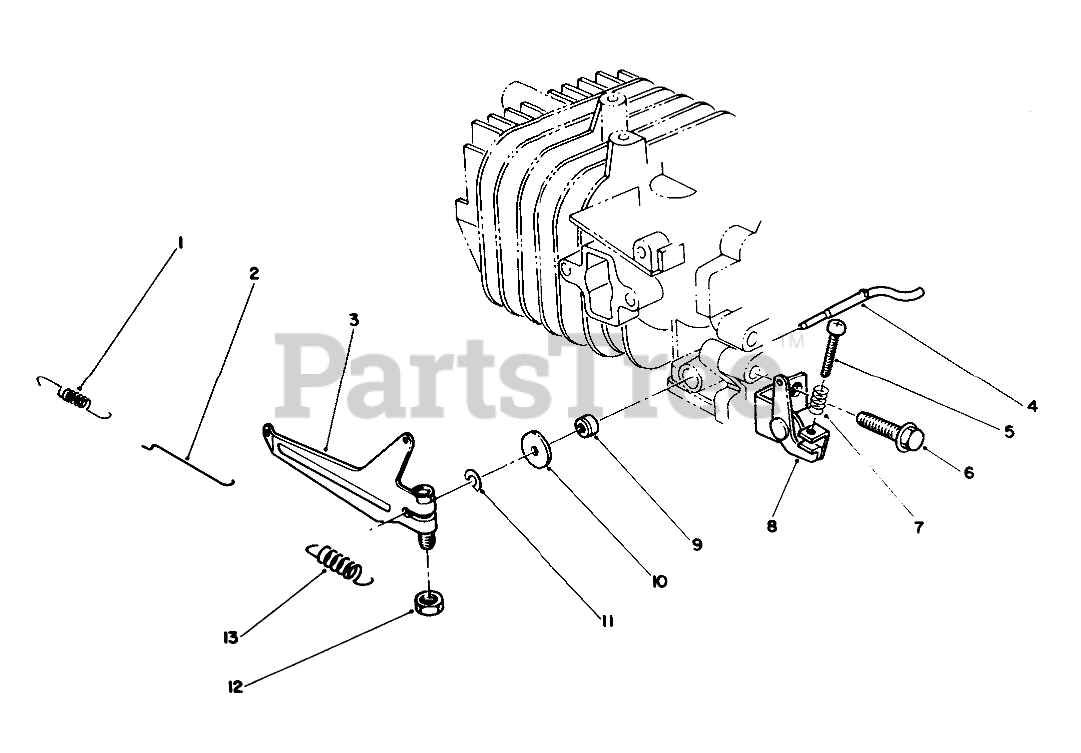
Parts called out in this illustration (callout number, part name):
1	CARB SPRING
2	CARB ROD
3	GOVERNOR ARM
4	SHAFT
5	SCREW
7	SPRING
8	GOV SPR BRKT
9	SEAL-OIL
10	WASHER
11	E-RING
13	GOV SPRING
